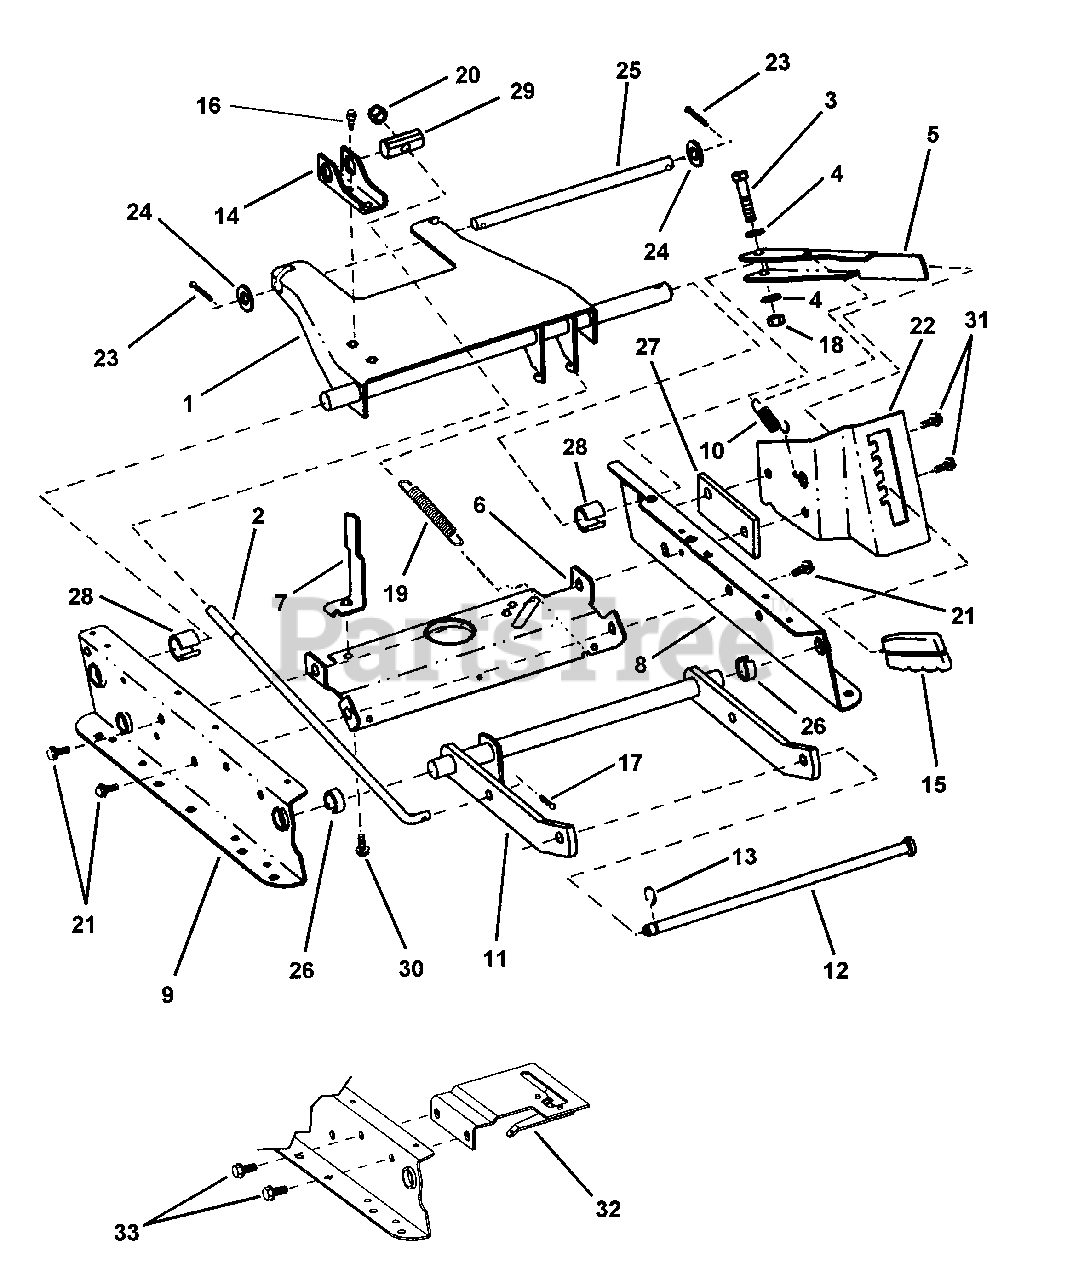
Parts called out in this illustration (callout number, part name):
1	ARM, Rear Lift
2	ROD, Leveling
3	SCREW, 3/8-24 x 1-3/4" Hex Head Cap, Grade 5
4	WASHER, 13/32" Flat
5	LEVER, Height of Cut
6	BRACE, Top
7	GUIDE, Belt
8	RAIL, Deck Lift, Left Hand
9	RAIL, Deck Lift, Right Hand
10	SPRING, Lever
11	ARM, Front Lift, Non-Adjustable (Weldment)
12	ROD, Support
13	SNAP RING, 7/16"
14	ARM, Leveling
15	GRIP, Height Adjustment Lever
16	SCREW, 5/16-18 x 5/8" Self-Tapping (Torx)
17	PIN, 1/8 x 3/4" Cotter
18	NUT, 3/8-24 Hex Center Lock
19	SPRING, Assist
20	NUT, 3/8-24 Hex Nyloc
21	SCREW, 3/8-16 x 5/8" Hex Washer Self-Tap
22	DETENT, Height Adjust
23	PIN, 1/8" x 1-1/4" Cotter
24	WASHER, 1/2" Flat
25	SHAFT, Rear Lift
26	RING, Red
27	DETENT, Spacer
28	RING, White
29	PIVOT, Leveling
30	SCREW, 5/16-18 x 5/8" Self-Tap
31	SCREW, 3/8-16 x 1" Hex Washer Self-Tap
32	ASSEMBLY, Clutch Plate
33	SCREW, 5/16-18 x 1/2" Hex Washer Self-Tap
